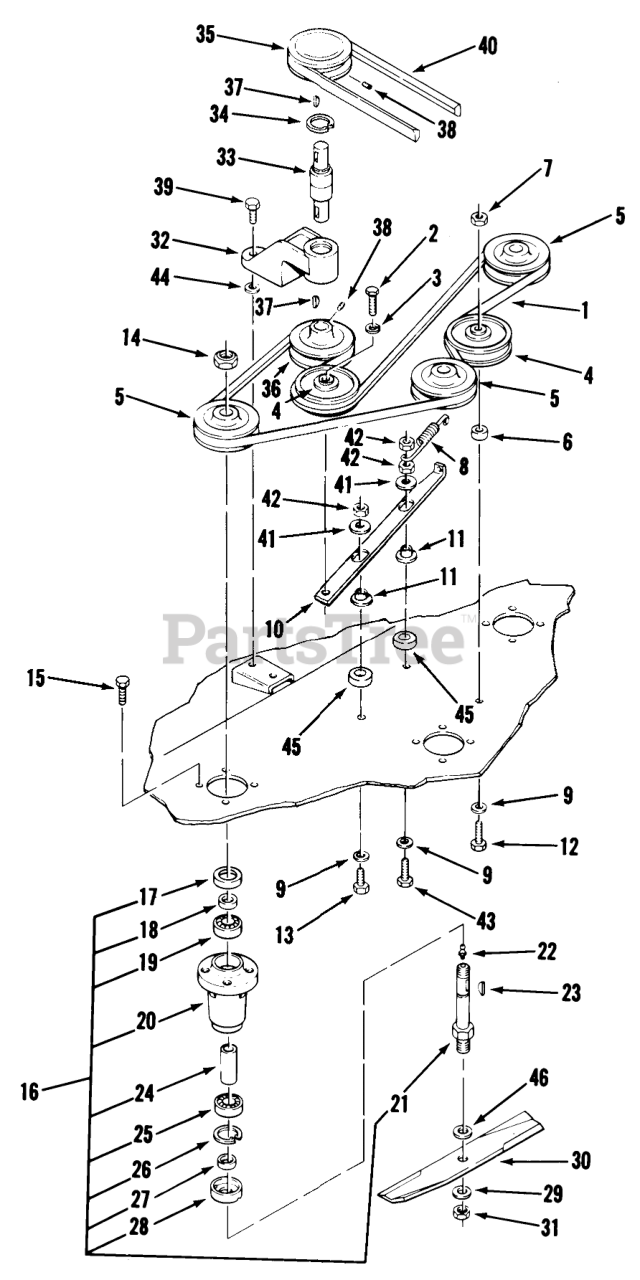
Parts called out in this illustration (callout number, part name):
1	V-BELT
2	BOLT HEX SPECIAL
2	Bolt
3	LOCKWASHER
4	Idler Pulley
5	PULLEY-BLADE DRIVE
6	SPACER
7	Nut
8	SPRING-EXTENSION
9	WASHER
10	BAR-SLIDER
11	SPACER-BUSHING
12	Bolt
13	Bolt
13	BOLT
14	Nut
15	Bolt
16	Spindle Assembly
18	SPACER-SEAL
19	BEARING-BALL
20	HOUSING-SPINDLE
21	7" X 3/4" SHAFT.JAK
22	Grease Fitting
23	Hi-Pro Key 3/16 x 5/8
24	SPACER
25	BEARING-BALL
26	Ring-Snap
27	SPACER-BLADE
28	CUP-SPINDLE
29	SpeciaI Washer
30	14IN BLADE KIT
31	Nut
32	HOUSING DRIVE BRG R
33	BEARING-INT SHAFT
34	Snap Ring
35	PULLEY
36	PULLEY-SPLIT
37	KEY-WOODRUFF
38	Set Screw
39	Bolt
40	Drive Belt
41	WASHER
42	NUT
42	Nut
43	Bolt
44	WASHER
45	SPACER
46	Washer
